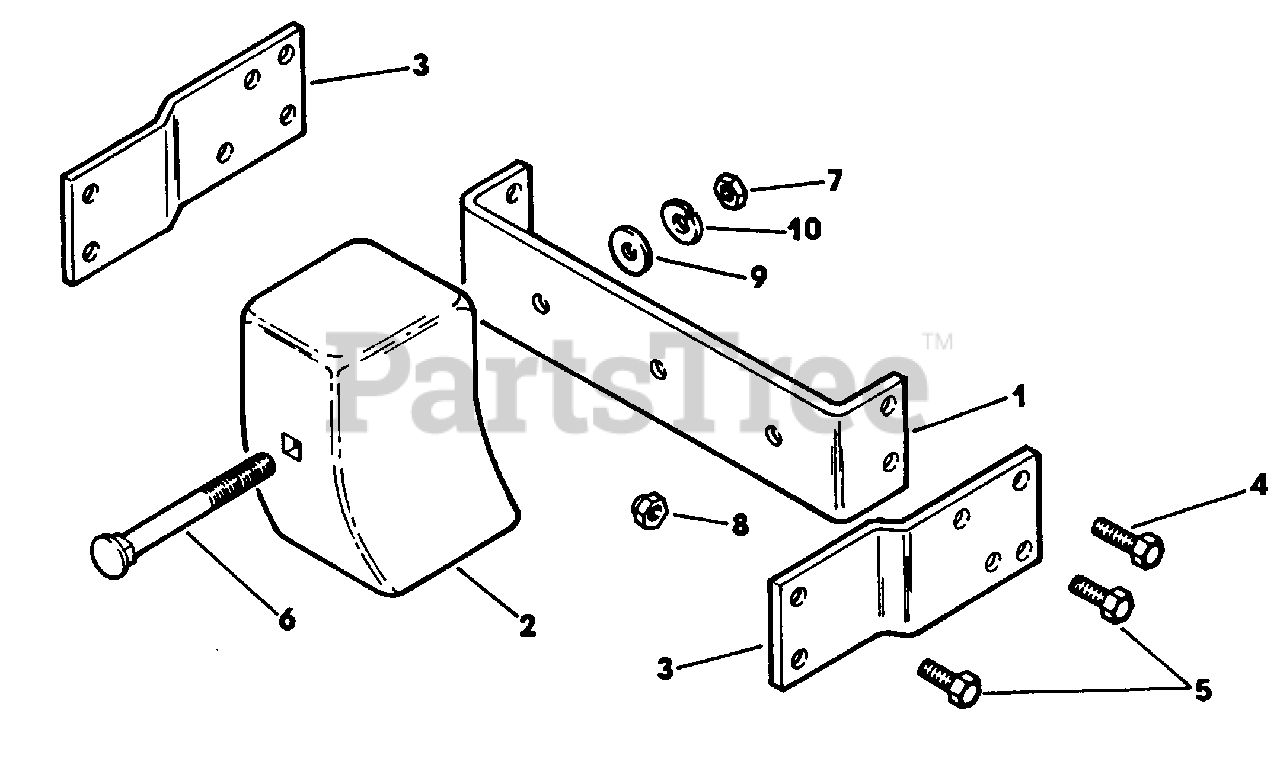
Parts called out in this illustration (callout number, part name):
1	Mounting Bracket
3	Thatcher Bracket
4	Cap Screw, Hex Hd
5	Cap Screw, Hex Hd
6	Bolt, Carriage
7	Nut, Hex
8	Nut, Hex Cone Lock
9	Washer, Flat
10	Washer, Spring Lock
